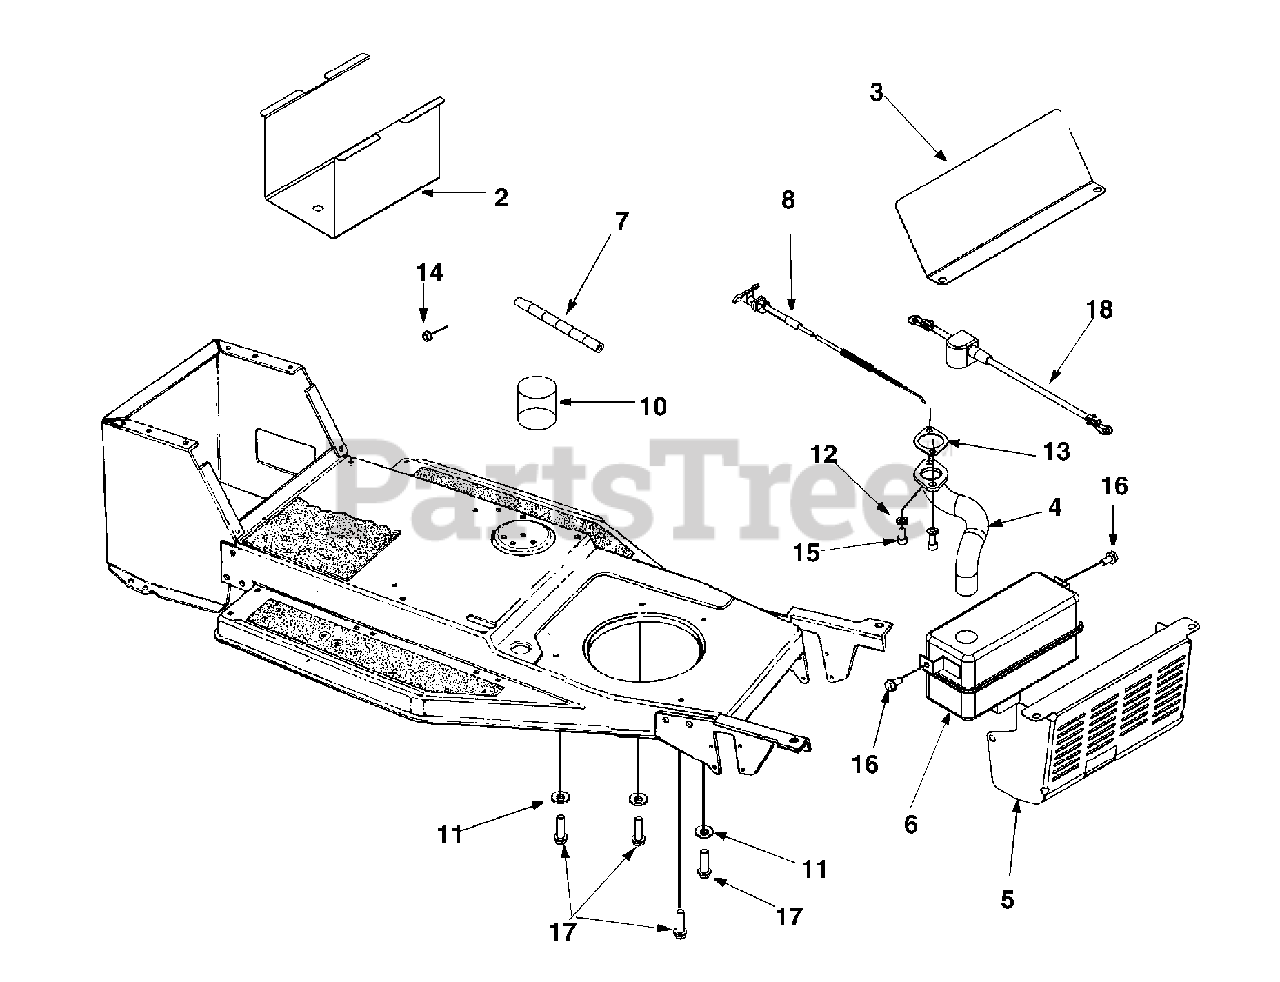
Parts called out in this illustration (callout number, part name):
4	Pipe Muffler
7	Fuel Line hose
8	Choke Control
10	SAE 30W Motor Oil
11	Flat Washer .38 I.D. x .93 O.D. x .110
12	Lock Washer 5/16
13	Gasket, Exhaust
14	Hex Nut 1/4-20
15	Socket Head Screw 5/16-18 x .625
16	Hex Wash. Head TT Screw 5/16-18 x .62
17	Hex Wash Hd. Self-Tapping Screw 3/8-16 x 1.25
18	Wire Assembly
